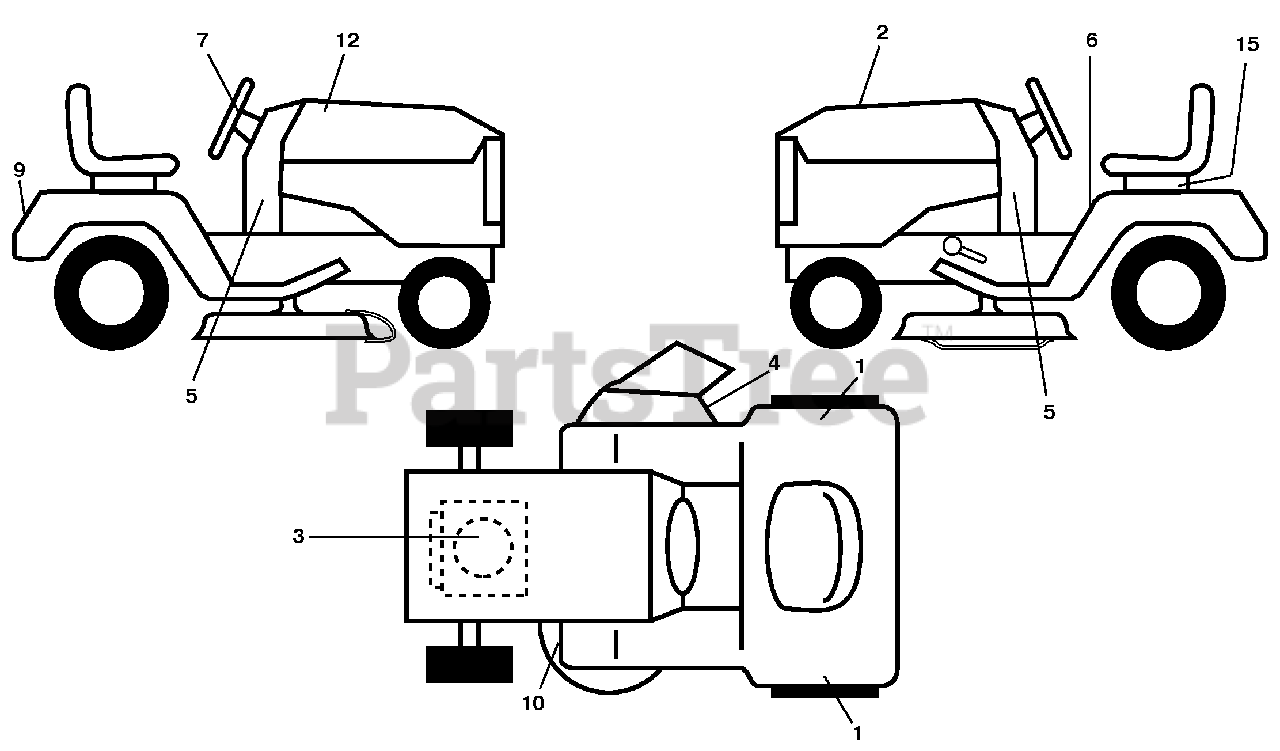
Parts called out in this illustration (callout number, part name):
1	Decal, Fender RH/LH Set
2	Decal, Replacement
3	Decal, Engine HP
4	Decal, Warning
5	Decal, Dash Lower
6	Decal, Fender Warning (E&F)
7	Decal, Ins Str Wh
9	Decal, Fender
10	Decal, V-Belt Sch.
12	Decal, Hood RH/LH
15	Decal, Caution, Battery
15	Pad Footrest RH
15	Pad Footrest LH
15	Decal, Handle Lft Height Adj.
15	Manual, Operator's, English & French
15	Manual, Parts, English & French
15	Manual, Operator's Spanish
